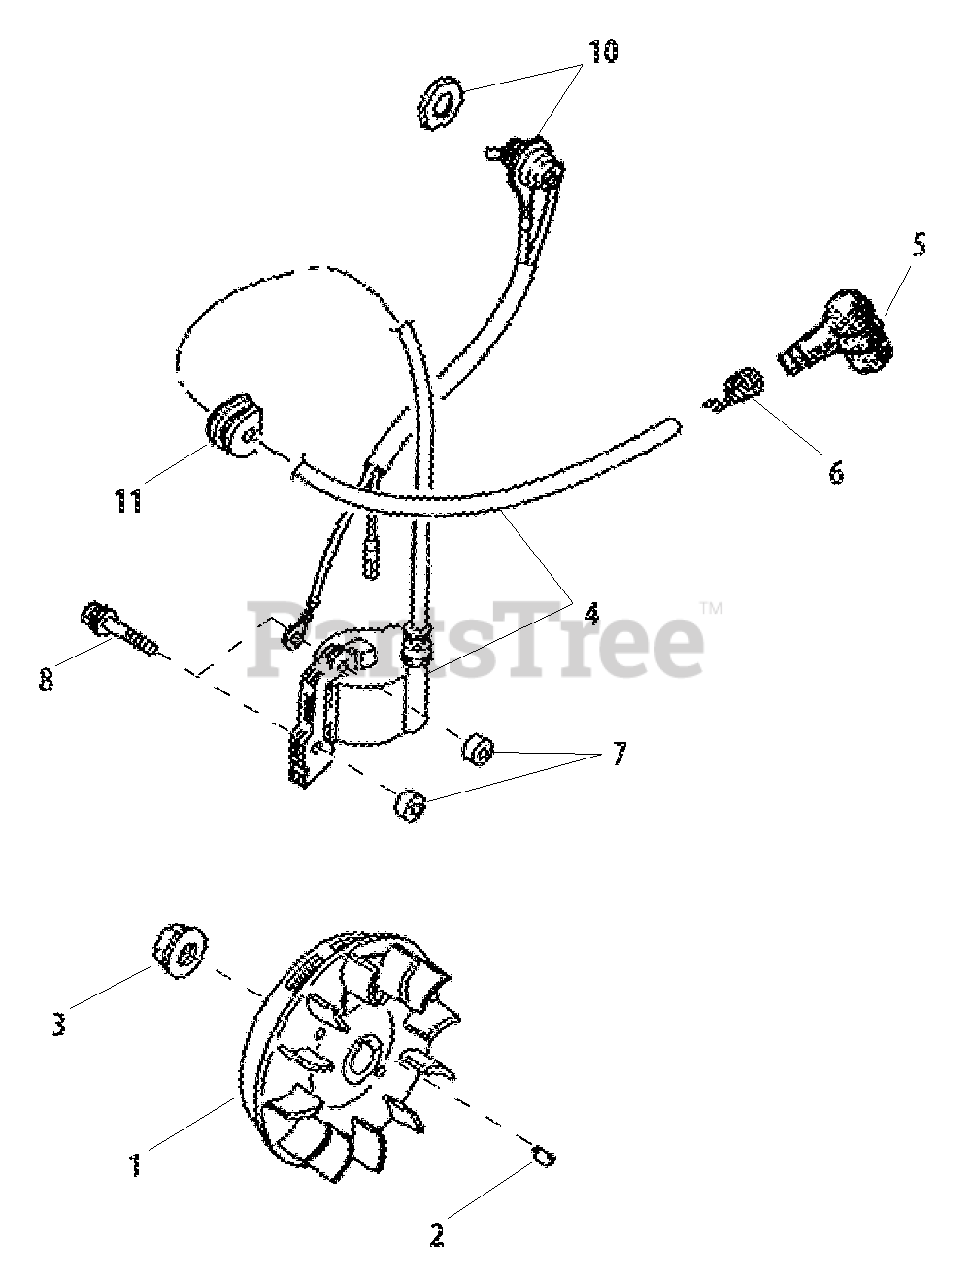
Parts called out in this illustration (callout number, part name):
1	FLYWHEEL
2	KEY - 3X10
3	NUT - 8
4	IGNITION COIL ASSY
5	CAP, SPARK PLUG
6	TERMINAL, SPARK PLUG CAP
7	INSULATOR
8	SCREW - 4X26
10	SWITCH
11	GROMMET
